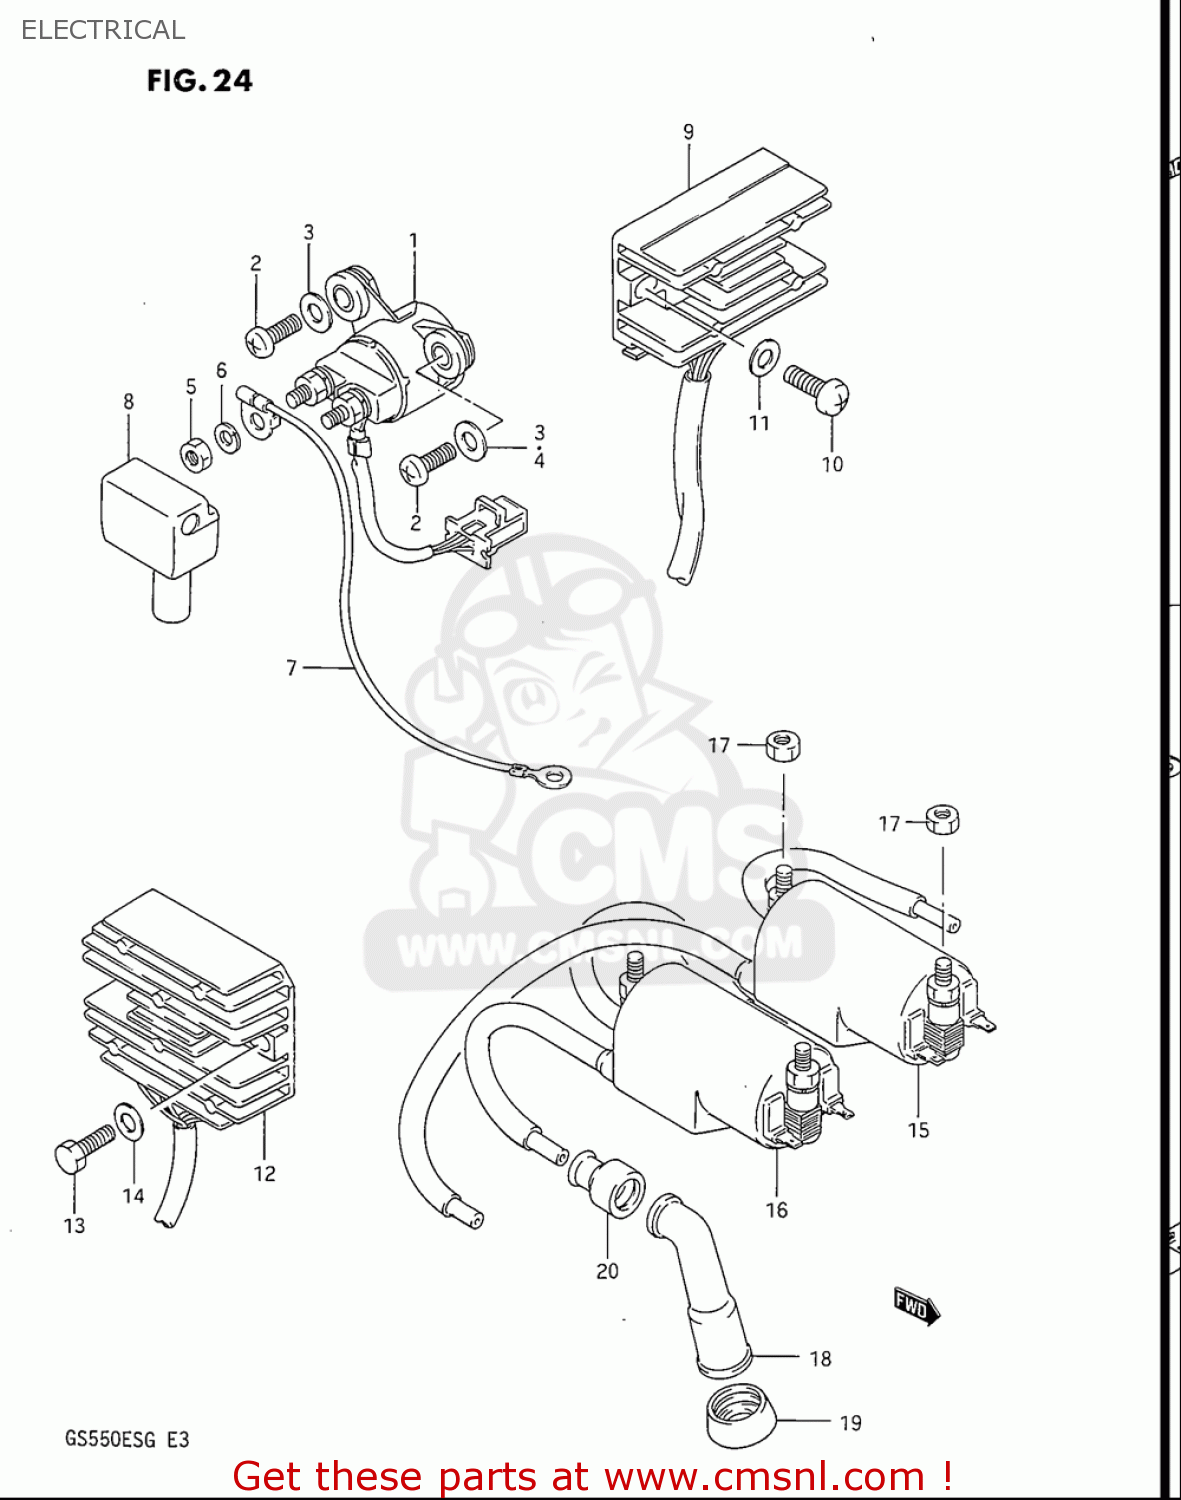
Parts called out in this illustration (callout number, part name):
1	RELAY ASSY,STARTING MOTOR
2	SCREW
3	WASHER(6.5X18X1.6)
4	WASHER
5	NUT
6	WASHER,LOCK
9	RECTIFIER ASSEMBLY
10	SCREW
11	WASHER
12	RECTIFIER ASSEMBLY
13	SCREW(6X20)
14	WASHER
15	COIL ASSY,IGNITION
16	COIL ASSY,IGNITION
17	NUT
18	CAP ASSY,SPARK PLUG
19	SEAL,SPARK PLUG
20	SEAL,HIGH TENSION CORD
